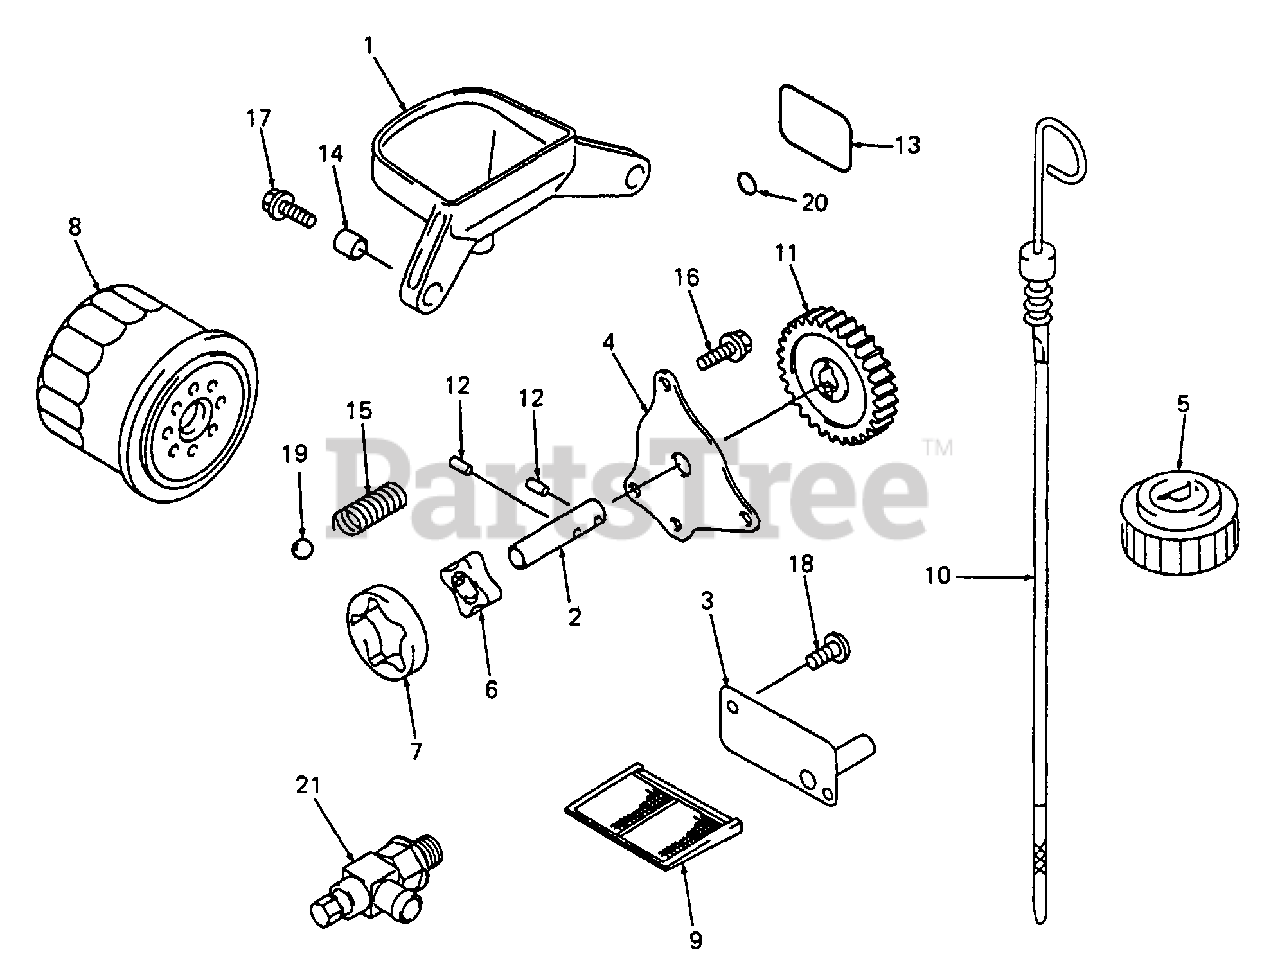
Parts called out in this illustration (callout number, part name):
1	Receiver, Oil
2	Shaft
5	Cap, Oil Filler
6	Rotor, Pump Inner
7	Rotor, Pump Outer
8	Element, Oil Filter
9	Screen, Oil Filter
10	Dipstick, Engine Oil
14	Collar, 8.2 x 10 x 10
15	Spring, Relief Valve
16	Bolt, Flanged
17	Bolt, Flanged
19	Ball, Steel, 13/32
